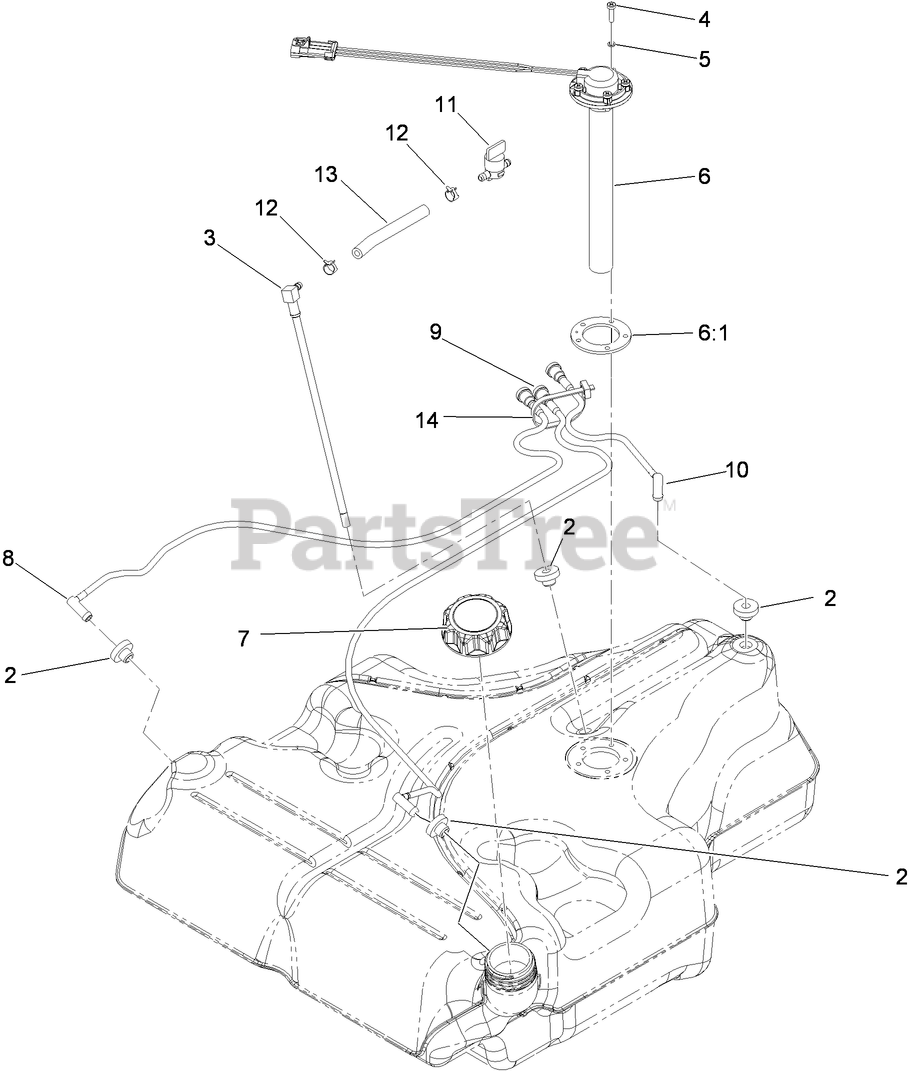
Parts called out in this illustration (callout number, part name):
2	BUSHING
3	FUEL LINE KIT (WITH GROMMET)
4	SCREW-PAN
5	WASHER-LOCK
6	SENDER-LEVEL, FUEL
6:1	GASKET-SENDER, FUEL
7	CAP-FUEL
8	RH VENT LINE KIT (WITH GROMMET)
9	LH VENT LINE KIT (WITH GROMMET)
10	REAR VENT LINE KIT (WITH GROMMET)
11	VALVE-FUEL
12	CLAMP-HOSE
13	HOSE-FUEL
14	TIE-PLASTIC
